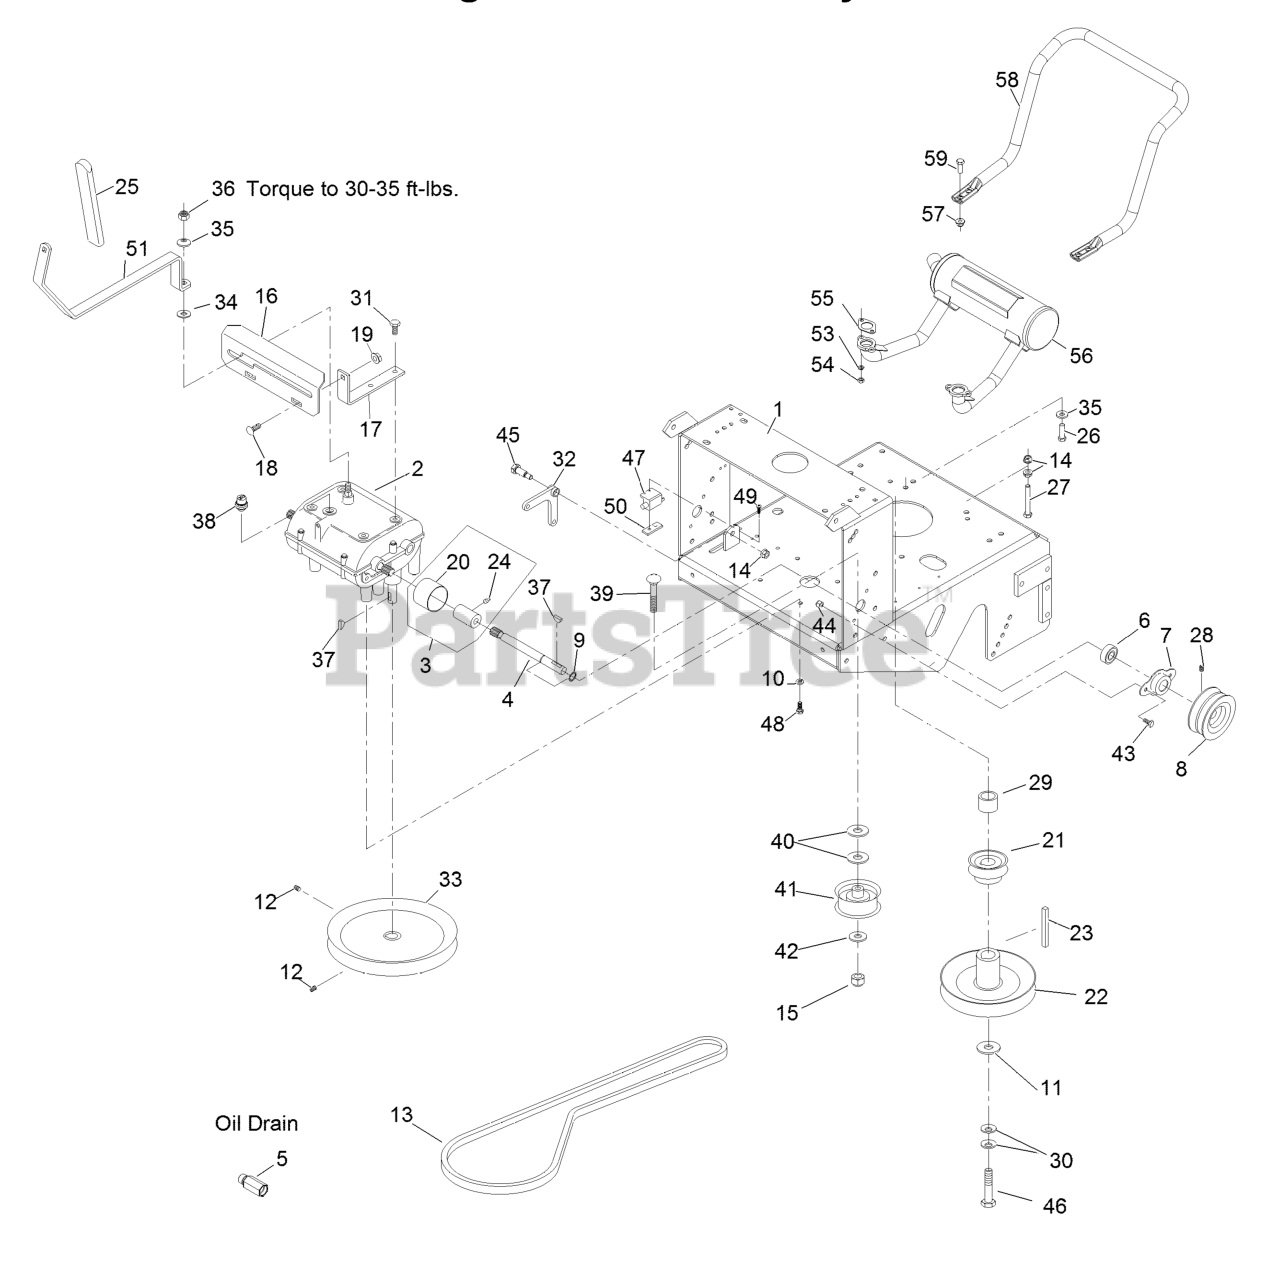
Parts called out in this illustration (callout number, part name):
1	ASM, METRO ENGINE DECK W/
3	ASM,COUPLER/ZERK
4	SHAFT-TRANSMISSION
5	ADAPTER
6	BEARING-SHAFT
7	FLANGE-OUTPUT
8	SHEAVE-TRANSMISSION
9	RING-RETAINING
10	WASHER-LOCK
12	SCREW-HSH
13	BELT,TRANS DRIVE
14	NUT-HHF, WHIZ
15	NUT-LOCK, NI
16	PLATE,SHIFTER W/DECAL
17	BRACKET-PLATE, SHIFT
18	BOLT-CARR
19	NUT-HF, NI
20	GUARD-COUPLER
21	SHEAVE-TRANSMISSION
24	FITTING-GREASE
25	GRIP,FOAM
26	SCREW-HH
27	SCREW-HH
28	SETSCREW
29	SPACER-CLUTCH
30	WASHER-SPRING
31	SCREW-THD ROLL, HWH
32	BELLCRANK
33	SHEAVE-TRANSMISSION
35	WASHER-BELLEVILLE
36	NUT-LOCK
37	KEY-WOODRUFF
38	SWITCH-START, NEUTRAL
39	SCREW-HH
40	WASHER-FLAT
42	WASHER-FLAT
43	SCREW-HH
44	NUT-LOCK, NI
45	BOLT-SHOULDER
46	SCREW-HH
47	SWITCH-OPEN, NORMALLY
48	SCREW-HH
49	SCREW-PPH
50	PLATE-TAPPED
51	ASM,SHIFT LEVER
53	WASHER-LOCK
55	GASKET-EXHAUST
56	MUFFLER-HORIZONTAL, OFFSE
57	NUT-HF, NI
58	GUARD-MUFFLER
59	SCREW-HH
